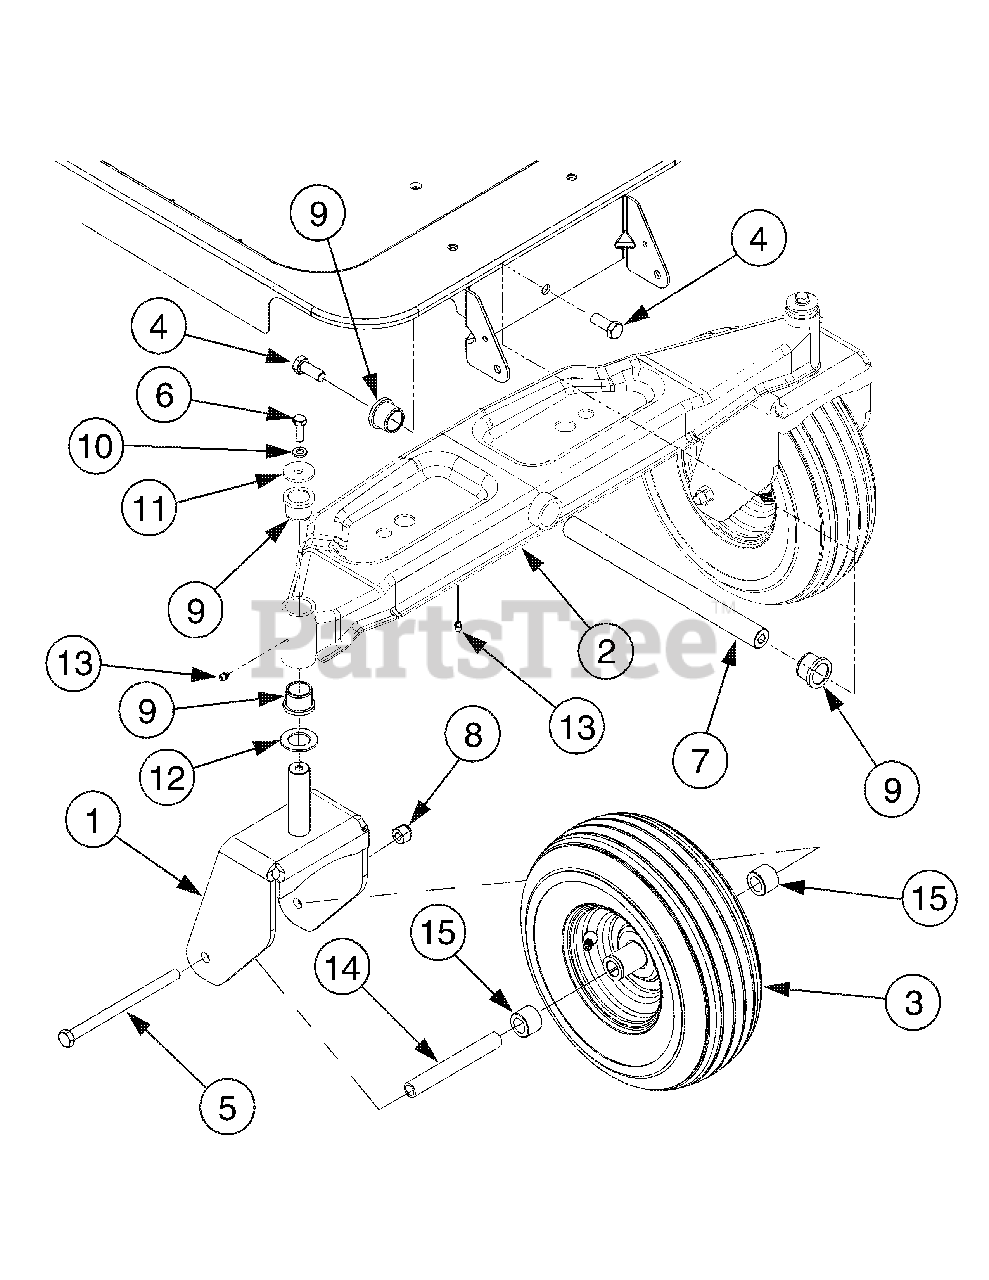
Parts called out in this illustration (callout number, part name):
5	Hex Cap Screw 1/2-20 x 7.25 Gr. 5
6	Hex Screw 3/16 x 1.00
7	Axle Shaft
8	Hex Insert Lock Nut 1/2-13 Gr.B
9	Flange Bearing 1.0 x 1,246
10	L-Wash 3/8 ID
11	Flat Washer .39 ID x 1.5 OD x .135
12	Flat Washer
13	Grease Fitting
14	Spacer .51 x .75 x 5.825
15	Hub .76 x 1.23 x .92
